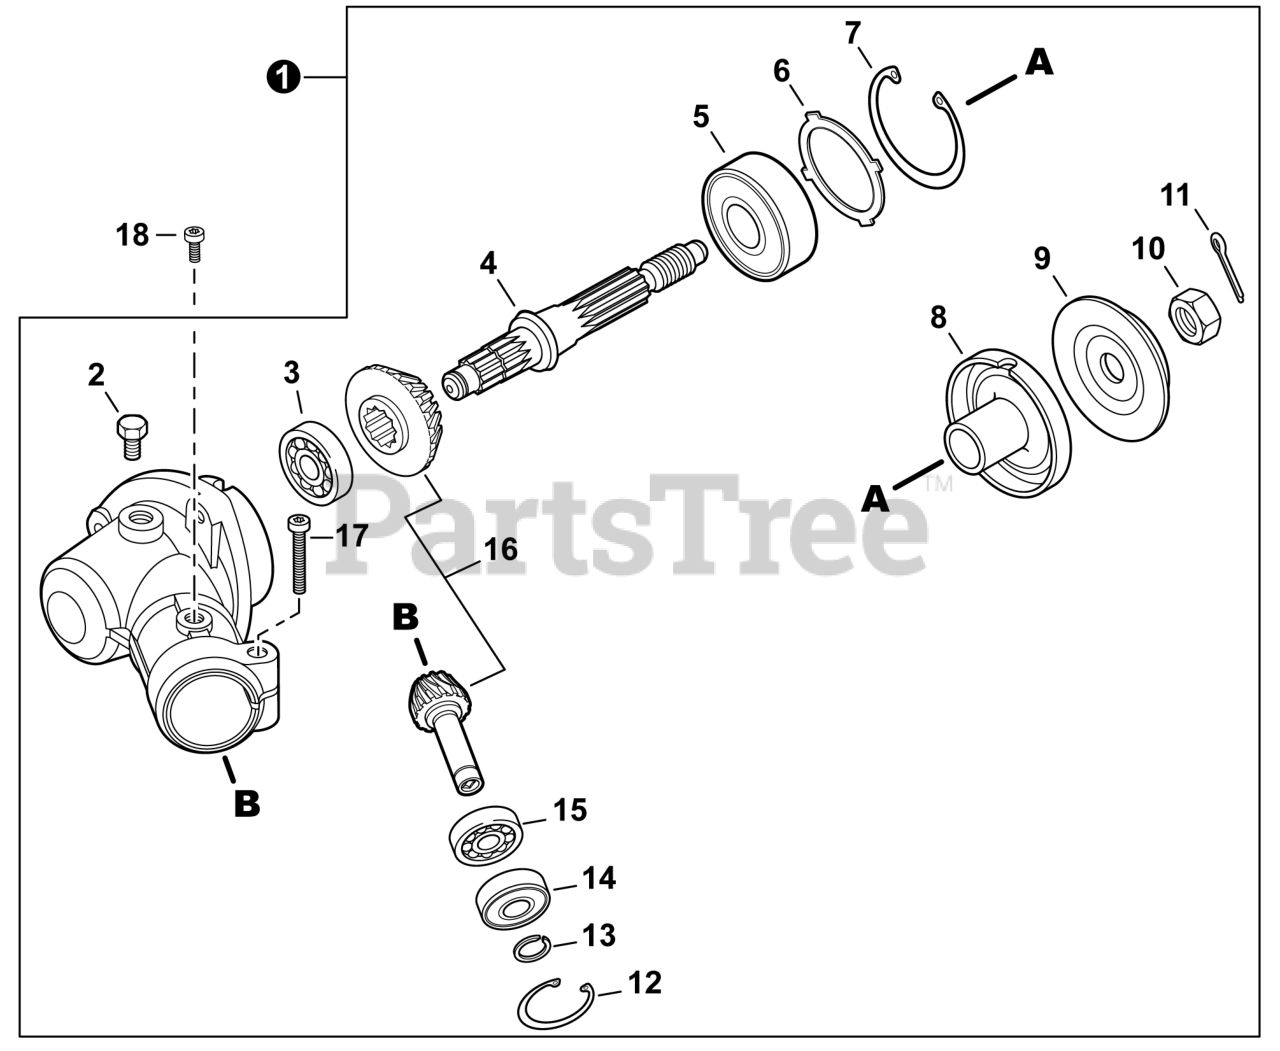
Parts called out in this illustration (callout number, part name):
1	GEAR CASE ASSY
2	BOLT M8x8
3	BEARING, BALL 629
4	SHAFT, GEAR
5	BEARING, BALL 6201
7	RING, SNAP 32
8	PLATE, ADAPTOR - UPPER
9	PLATE, ADAPTOR - LOWER
10	NUT 10x1.25 LH
11	PIN, COTTER 2x22
12	RING, SNAP 25
13	RING, SNAP 9
14	BEARING, BALL 609ZA
15	BEARING, BALL 609A
16	GEAR SET
17	BOLT, TORX 5x25
18	BOLT, TORX 5x12
